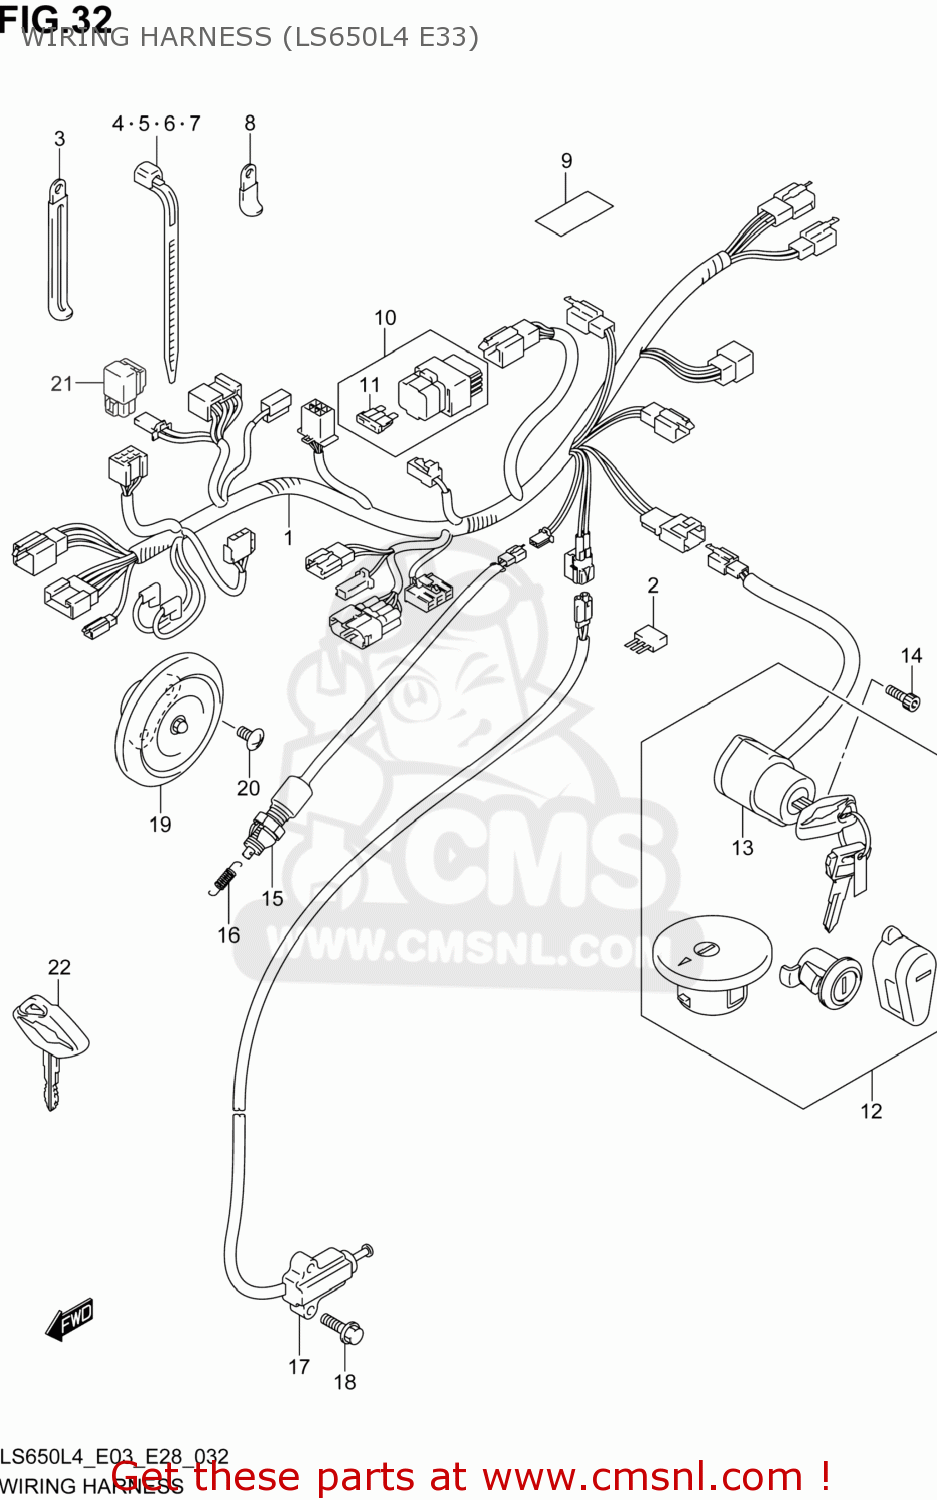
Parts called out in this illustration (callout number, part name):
1	HARNESS,WIRING
2	DIODE(STANLEY DE8804)
3	CLAMP(L:80)
4	CLAMP(L:95)
5	CLAMP(L:125)
6	CLAMP(L:165)
7	CLAMP(L:235)
8	CLAMP,WIRING HARNESS
9	COVER
10	BOX ASSY,FUSE
11	FUSE(20A)
12	LOCK SET
13	SWITCH ASSY,IGNITION
14	BOLT
15	SWITCH ASSY,STOP LAMP
16	SPRING
17	SWITCH ASSY,SIDE STAND WARNING
18	BOLT
19	HORN ASSY
20	SCREW
21	RELAY ASSY
22	KEY,BLANK(TYPE:C)
